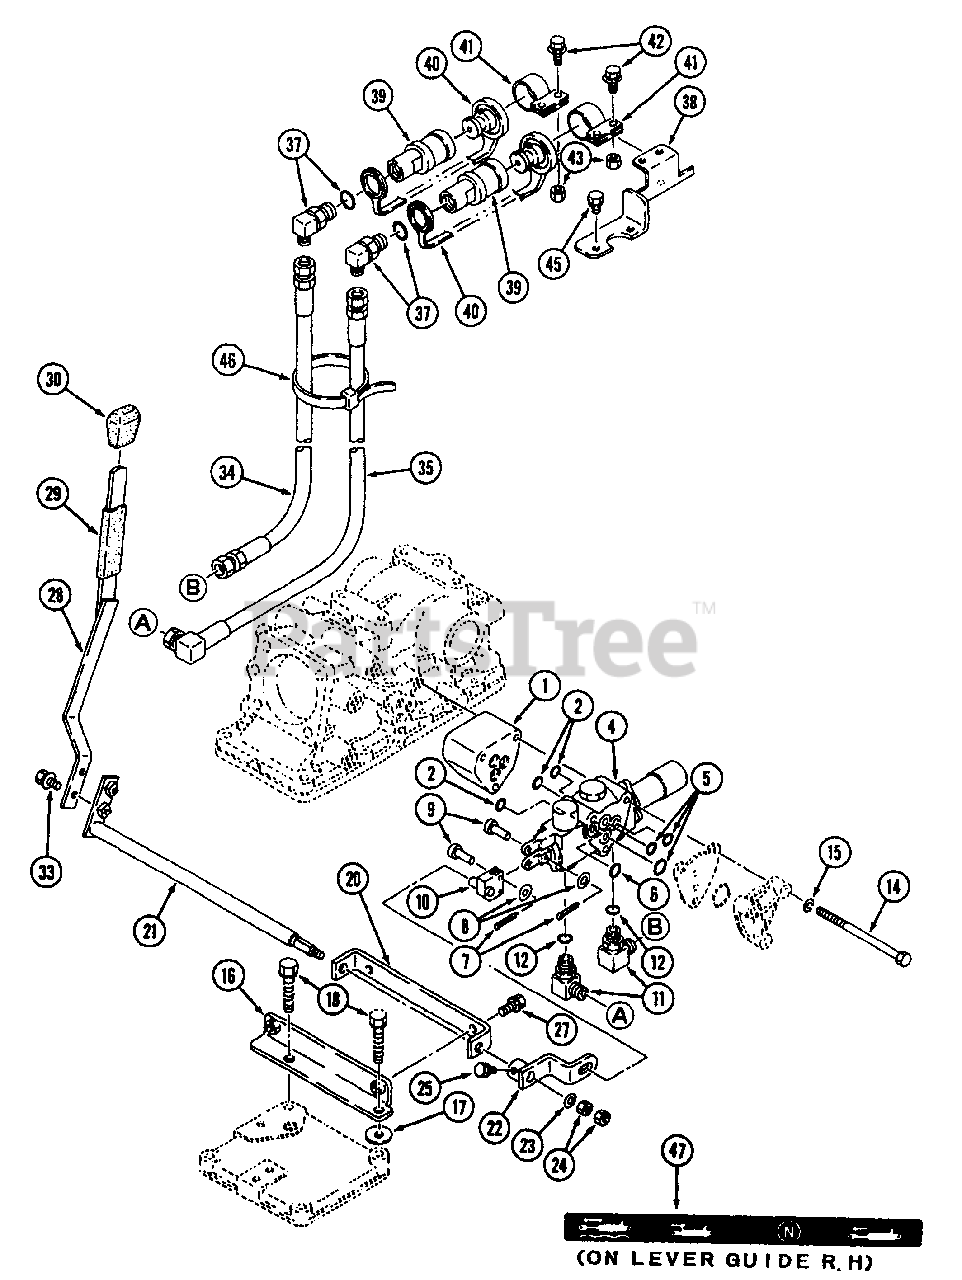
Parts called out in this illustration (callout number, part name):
4	Body
5	O-Ring
7	Pin,Split
28	Lever
39	Coupling
41	Clamp, Coupler
47	Label, Aux. Valve
